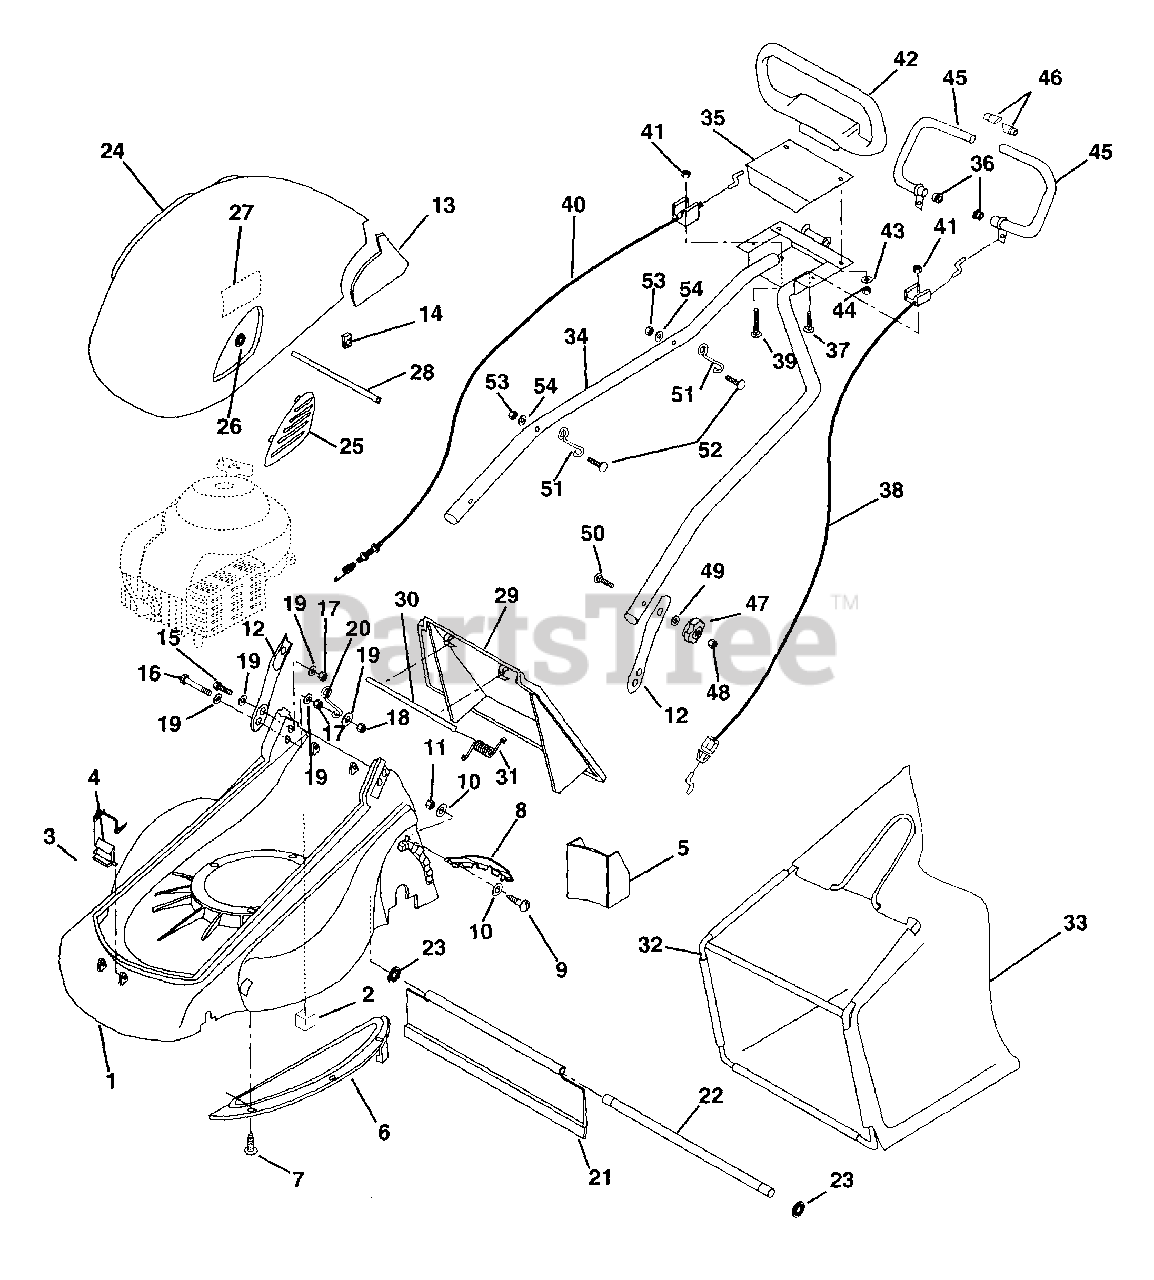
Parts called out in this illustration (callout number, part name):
1	DECK, MOWER 18"
2	SPACER, REAR AXLE GRAY
3	LATCH, COVER
4	SPRING, LATCH RETURN
5	PLUG, MULCHING
6	COVER, HEIGHT ADJMT ROD/SPRING
7	SCREW, KA 50X16
8	PLATE, REINFORCING HEIGHT ADJT
9	SCREW, M6X16
10	WSHR, 6.4X12.5X1.6
11	NUT, LK M6
12	SUPPORT, HANDLEBAR ORANGE
13	COVER, HANDLEBAR SUPPORT RIGHT
14	CLIP, HANDLEBAR SUPPORT COVER
15	BOLT, M8X20
16	BOLT, M8X30
17	NUT, M8
18	NUT, LK M8
19	WSHR, 8.4X17X1.6
20	GUIDE, ROPE
21	SHIELD, ECOBUG TRAILING BLK
22	ROD, TRAILING SHIELD
23	CLIP, STAR LOCK TRAILING SHLD
24	COVER, ENGINE
25	GRILL, EXHAUST
26	CLIP, EXHAUST GRILL
27	SHEET-HEAT REFLECTIVE 3X5
28	ROD, ENGINE COVER
29	DOOR, REAR
30	ROD, REAR DOOR HINGE
31	SPRING, REAR DOOR
32	FRAME, BAG
34	HANDLEBAR, ASSEMBLY WELDMENT
35	PLATE, COVER
36	BUSHING, TUBE PIVOT
37	BOLT, M6X16 CARRIAGE
38	CABLE, ENGINE BREAK
39	BOLT, M6X30 CARRIAGE
40	CABLE, TRANSMISSION CONTROL
41	NUT, M6
42	ARM, CONTROL
43	WSHR, 6.4X12.5X1.6
44	NUT, LK M8
45	LEVER, CONTROL WELDMENT
46	STOP, CONTROL LEVER
47	KNOB, HANDLEBAR FOLDING
48	NUT, M8 KNOB INSERT
49	WSHR, 8.4X17X1.6
50	BOLT, M8X55 CARRIAGE
51	GUIDE, ROPE
52	PINION/RATCHET-RH 15T
53	NUT, M6
54	WSHR, 6.4X12.5X1.6
